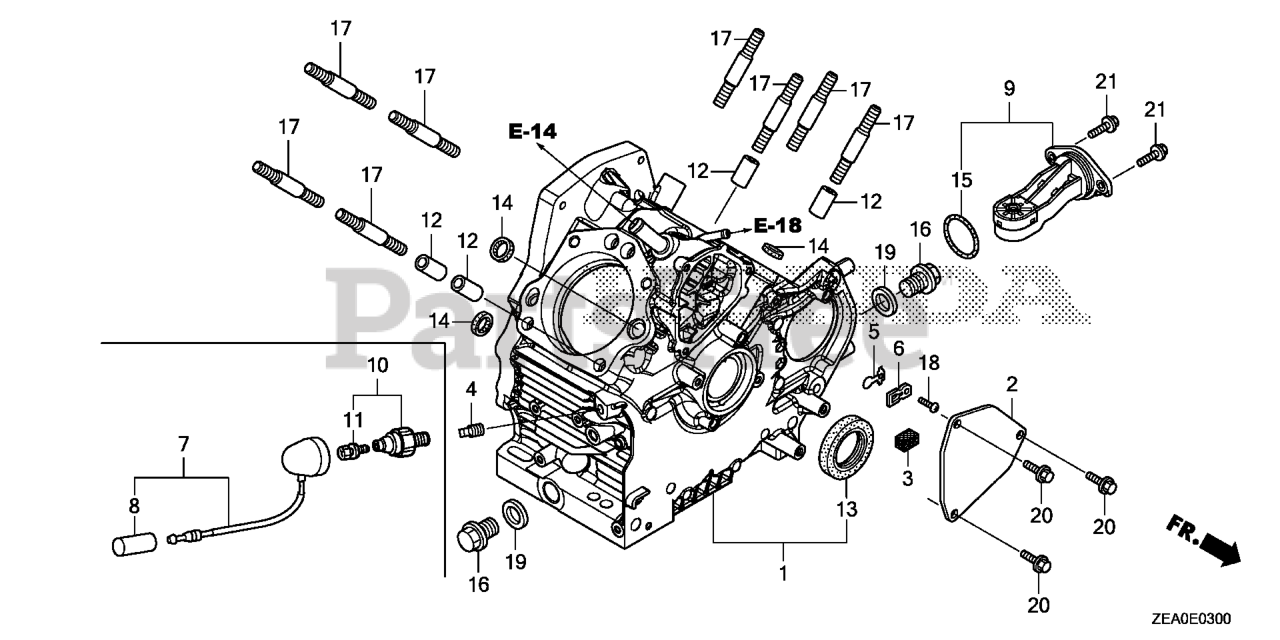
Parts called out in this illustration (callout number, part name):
1	CRANKCASE ASSY.
2	COVER, BREATHER
3	FILTER, BREATHER
4	BOLT, SEALING
5	VALVE, OIL OUTLET
6	PLATE, STOPPER
9	SWITCH ASSY., OIL LEVEL
12	PIN, DOWEL (12X20)
13	OIL SEAL (38X58X9)
14	GASKET, OIL PASSAGE
15	O-RING (37.9X2.4)
16	BOLT, DRAIN PLUG (20MM)
17	BOLT, STUD (10X40)
18	SCREW, PAN (3X8)
19	WASHER, DRAIN PLUG (20MM)
20	BOLT, FLANGE (6X14)
21	BOLT, FLANGE (6X16) Use from Engine SN 2056820.
